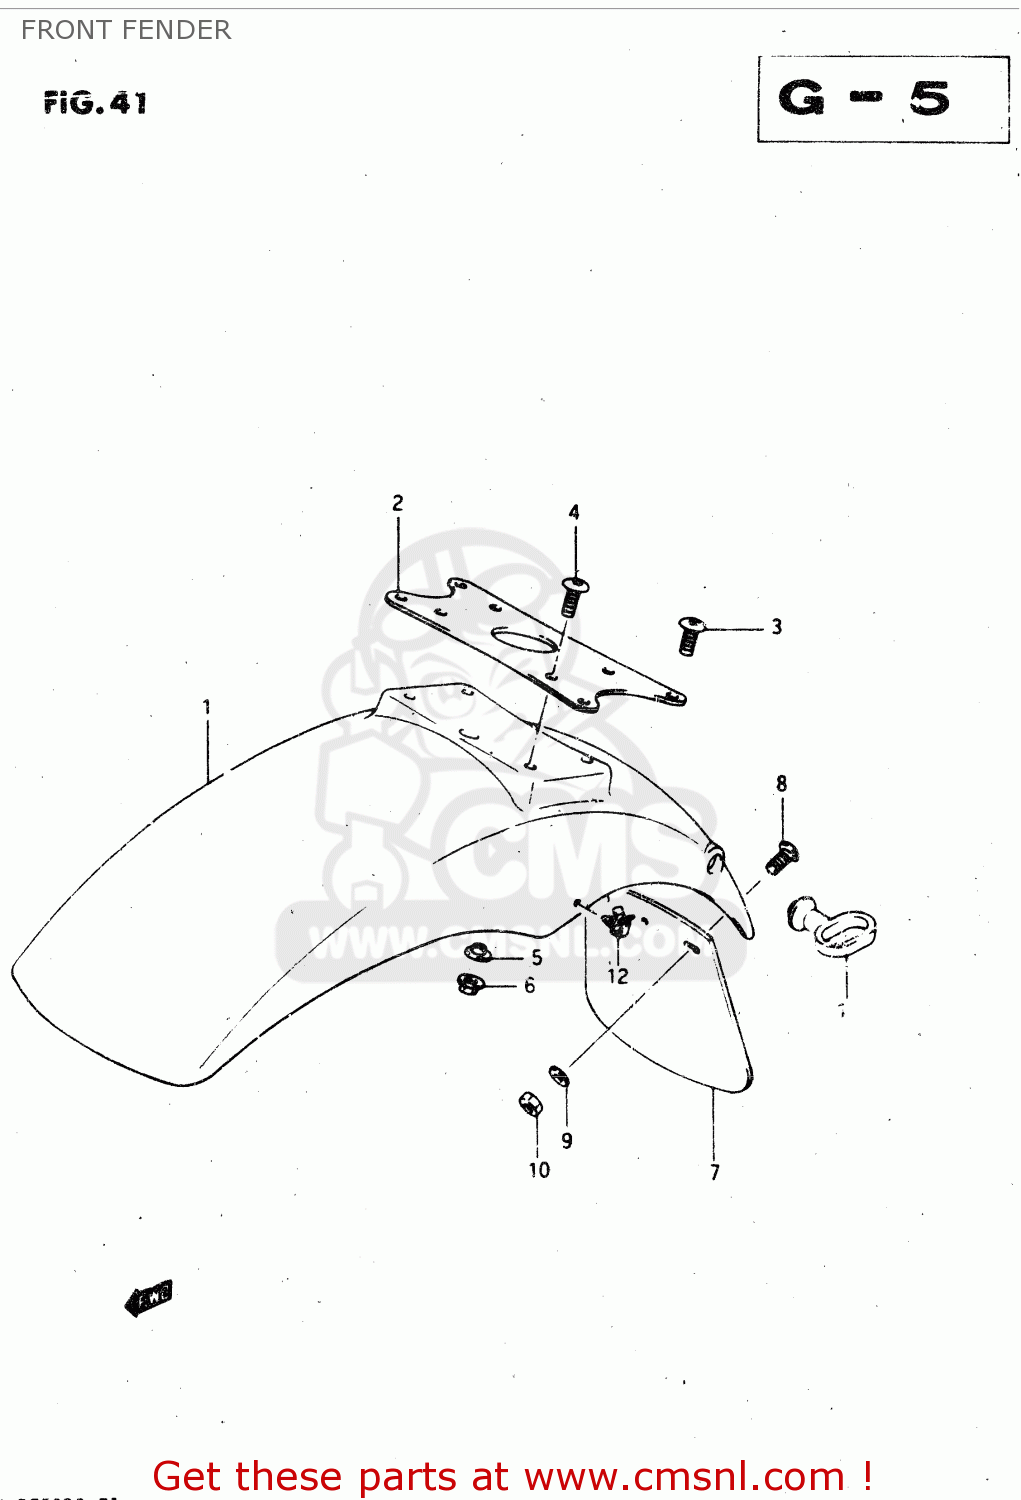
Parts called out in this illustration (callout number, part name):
1	FENDER, FRONT (WHITE)
2	BRACE,FRONT FENDER
3	SCREW(8X16)
4	SCREW(5X14)
5	WASHER
6	NUT
7	FLAP,MUD
8	SCREW
9	WASHER (5.5X16X1.2)
10	NUT
11	GUIDE,CABLE
12	CLIP
